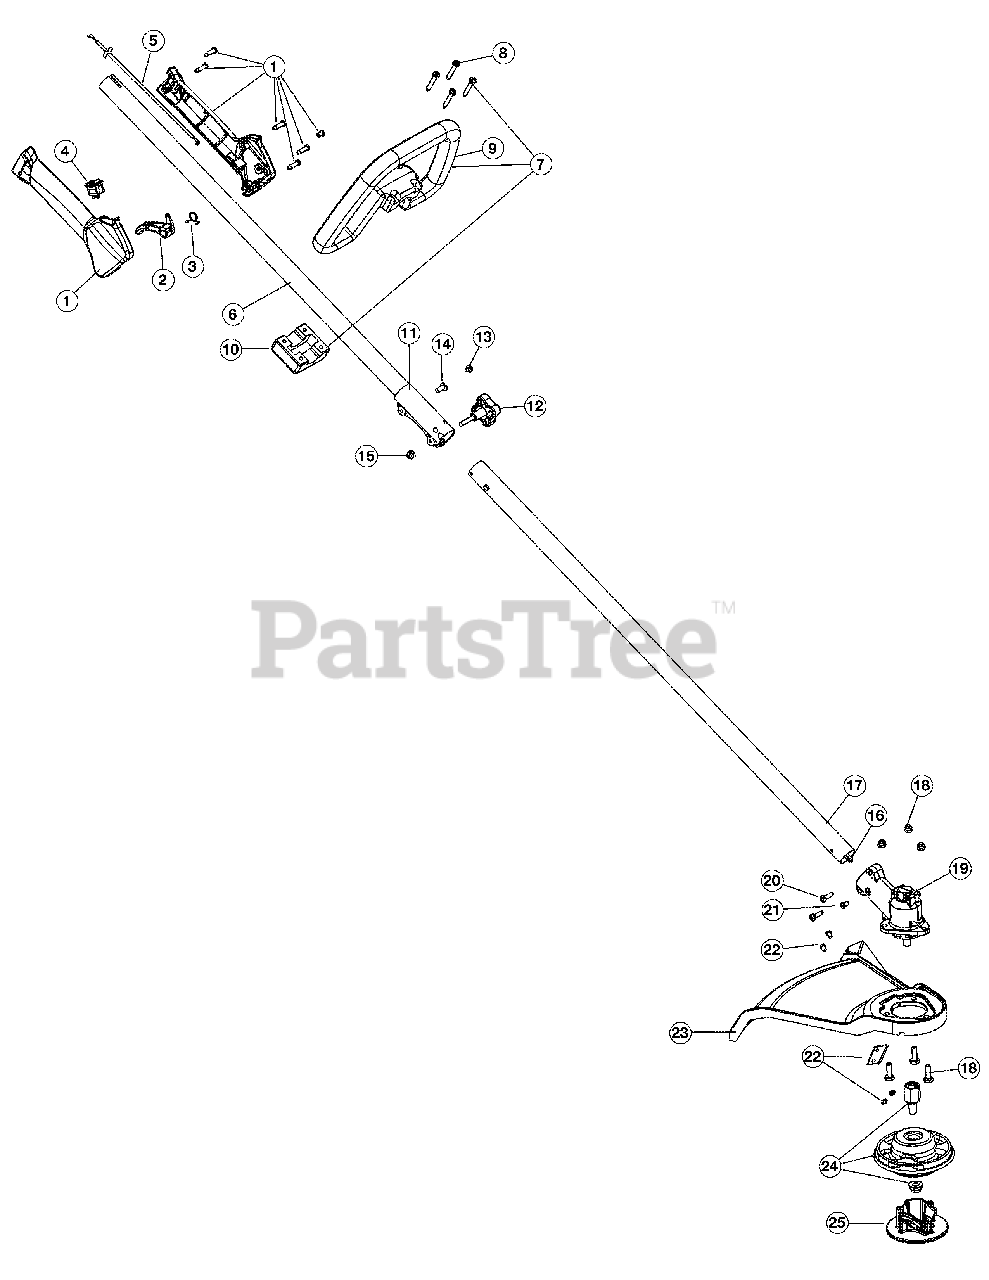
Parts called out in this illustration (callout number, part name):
1	Throttle Housing Assembly
2	Throttle Trigger
3	Throttle Trigger Spring
4	Switch Assembly
5	Throttle Cable Assembly
6	Upper Drive Shaft Housing
7	Deluxe D-Handle Assembly
9	D-Handle
10	D-Handle Base
11	Split Boom Coupler
12	Adjustment Knob
15	Nut
16	Lower Flexible Drive Shaft
17	Lower Drive Shaft Housing
18	Shield Mount Screw Assembly
19	Gearbox Assembly
20	Gearbox Screw
21	Anti-Rotation Screw
22	Blade Assembly
23	Shield Assembly
24	Cutting Head Assembly
25	Cutting Head Cap
